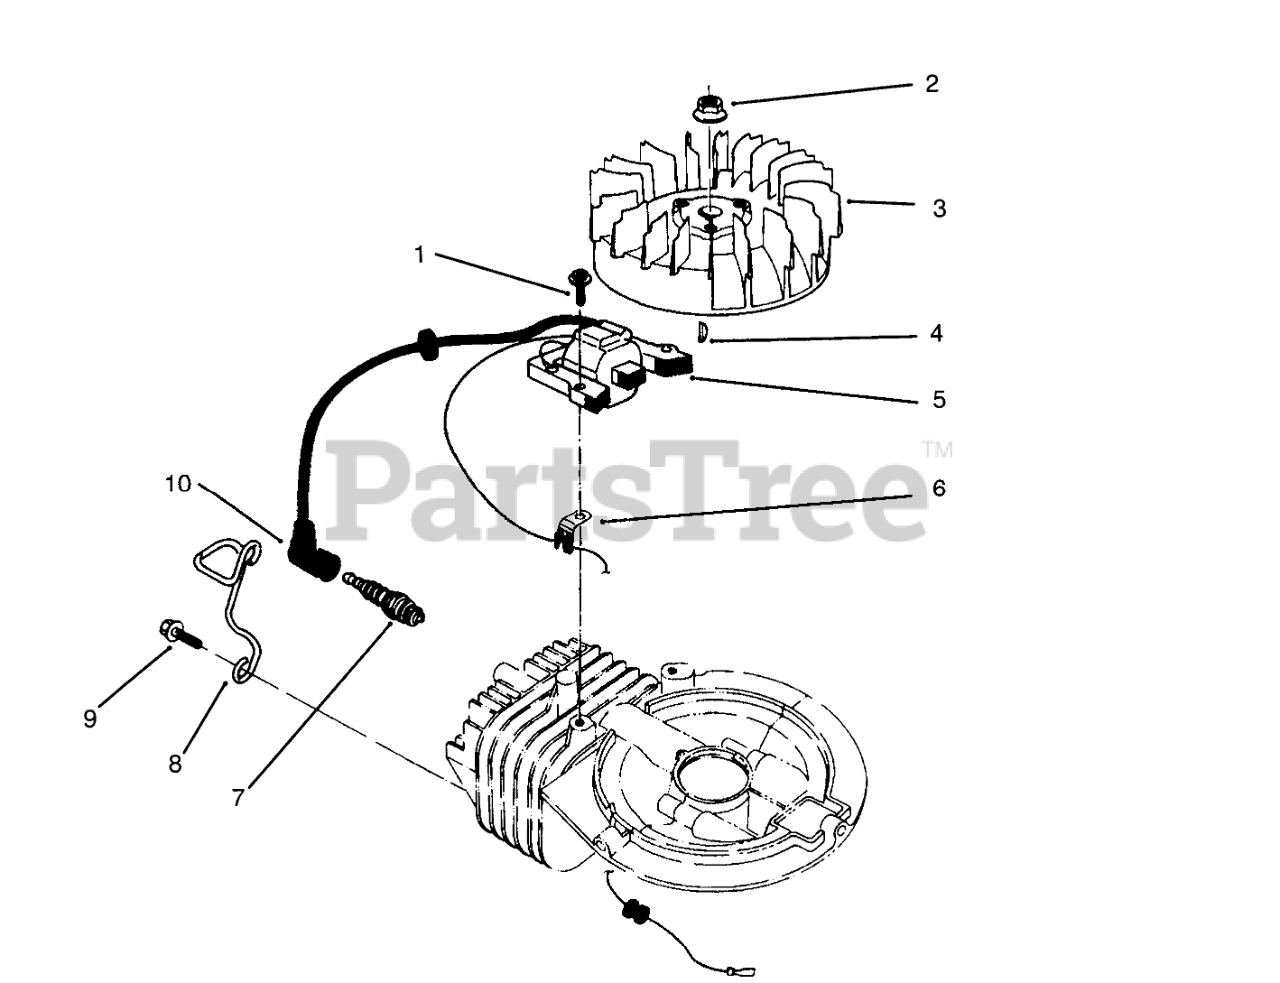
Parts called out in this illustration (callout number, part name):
1	SCREW
3	FLYWHEEL
5	COIL-MAGNETO
6	CLAMP
7	Sparkplug
8	PROTECTOR-PLUG
9	SCREW
10	CAP-SPARKPLUG
